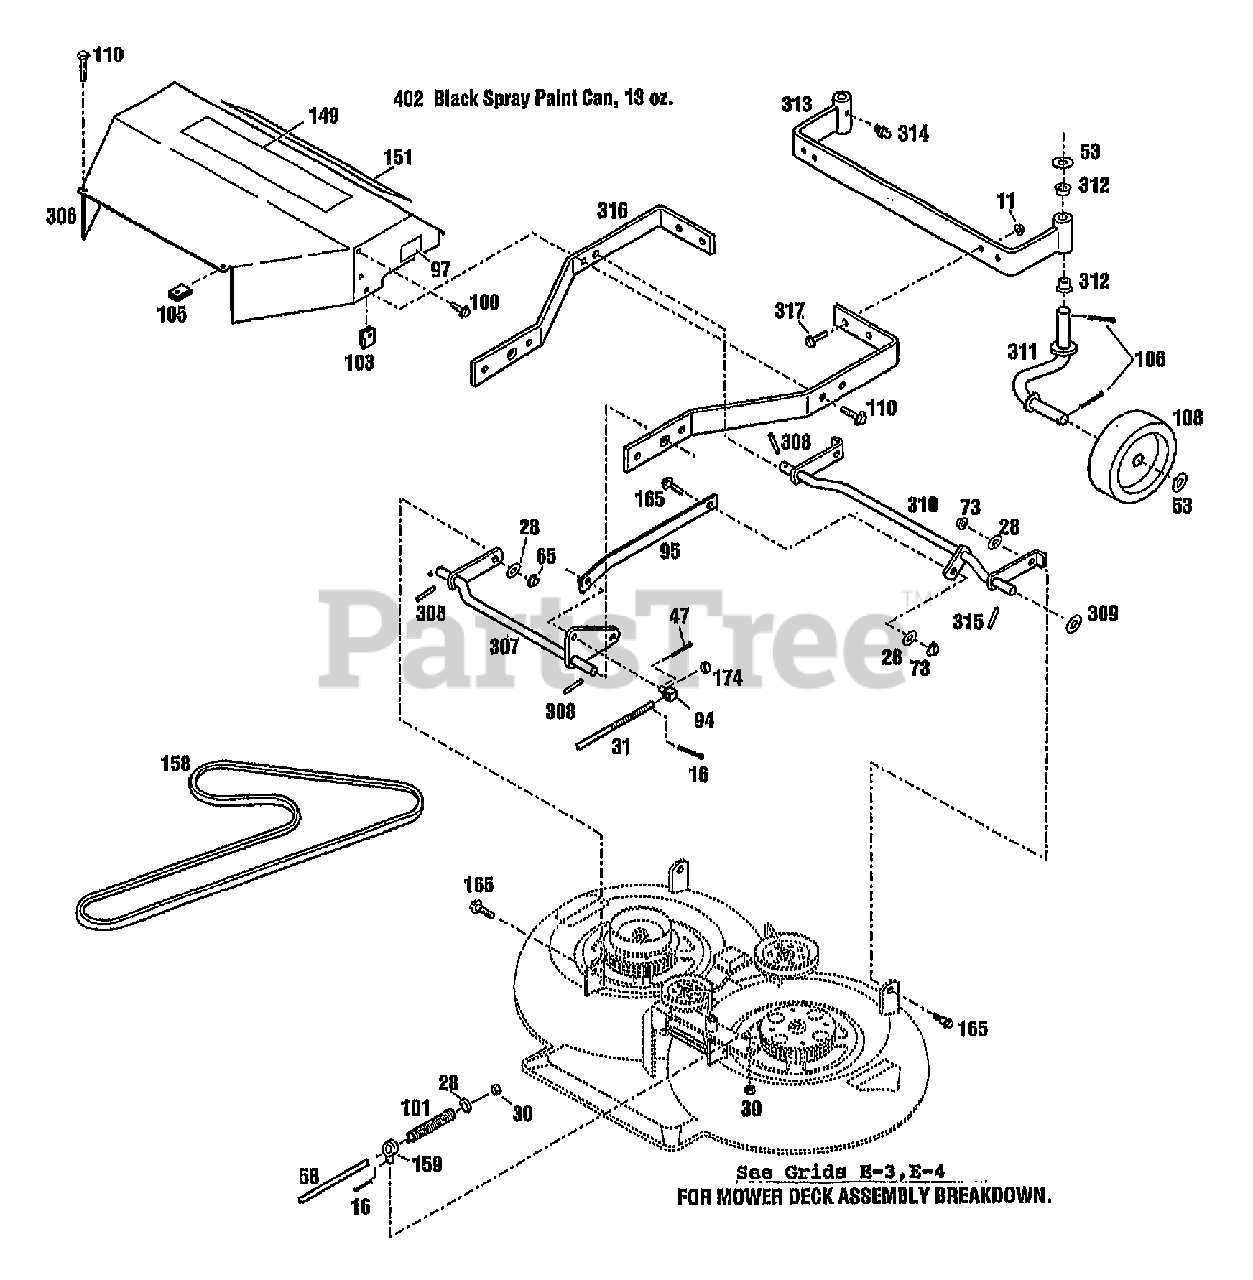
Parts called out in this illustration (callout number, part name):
11	NUT-HFLK 3/8-16 ZP
16	PIN-COTTER .093X.625
28	WASHER-FLAT 3/8 SAE
30	NUT-LOCK 3/8-16
31	ASSM-CRANK LIFT
47	PIN-COTTER .125 X .75 ZP
53	WASHER-1.25X.765X.049
58	ROD-LOWER BLADE
73	NUT-HEX/JAM 3/8-16 ZP
94	BLOCK-PIVOT ZP
95	BAR-LEVELER
97	DECAL-CUTTING HEIGHT
100	BOLT-TAP 8 X 3/8
101	SPRING-COMPRESS BLADE ROD
103	NUT 5/16-18 SPEED
105	NUT-SPEED
106	PIN-COTTER .125X1.5
108	GAUGE-WHEEL
110	SCR-HFLK 5/16-18X.75 ZP
149	DECAL-TROY BILT
151	DECAL-33" MULCHING
159	BOLT-EYE
165	SCR-SHLDR 3/8-16X.25 G5ZP
174	NUT-TOPLK .4375-14
306	COVER-BELT
307	ASSM-REAR LIFT
308	PIN-DRIVE .25X1.00
309	WASHER-1.305X.649X.098 ZP
310	ASSM-FRONT LIFT
311	ASSM-SPINDLE
313	SUPPORT-GAGE
314	FITTING-GREASE 1/4-28X2.00
315	PIN-DRIVE .25X3.0 ZP
316	SUPPORT-MOWER
317	SCR-HFLK 3/8-16X1.00 ZP
402	PAINT-BLACK SPRAY
